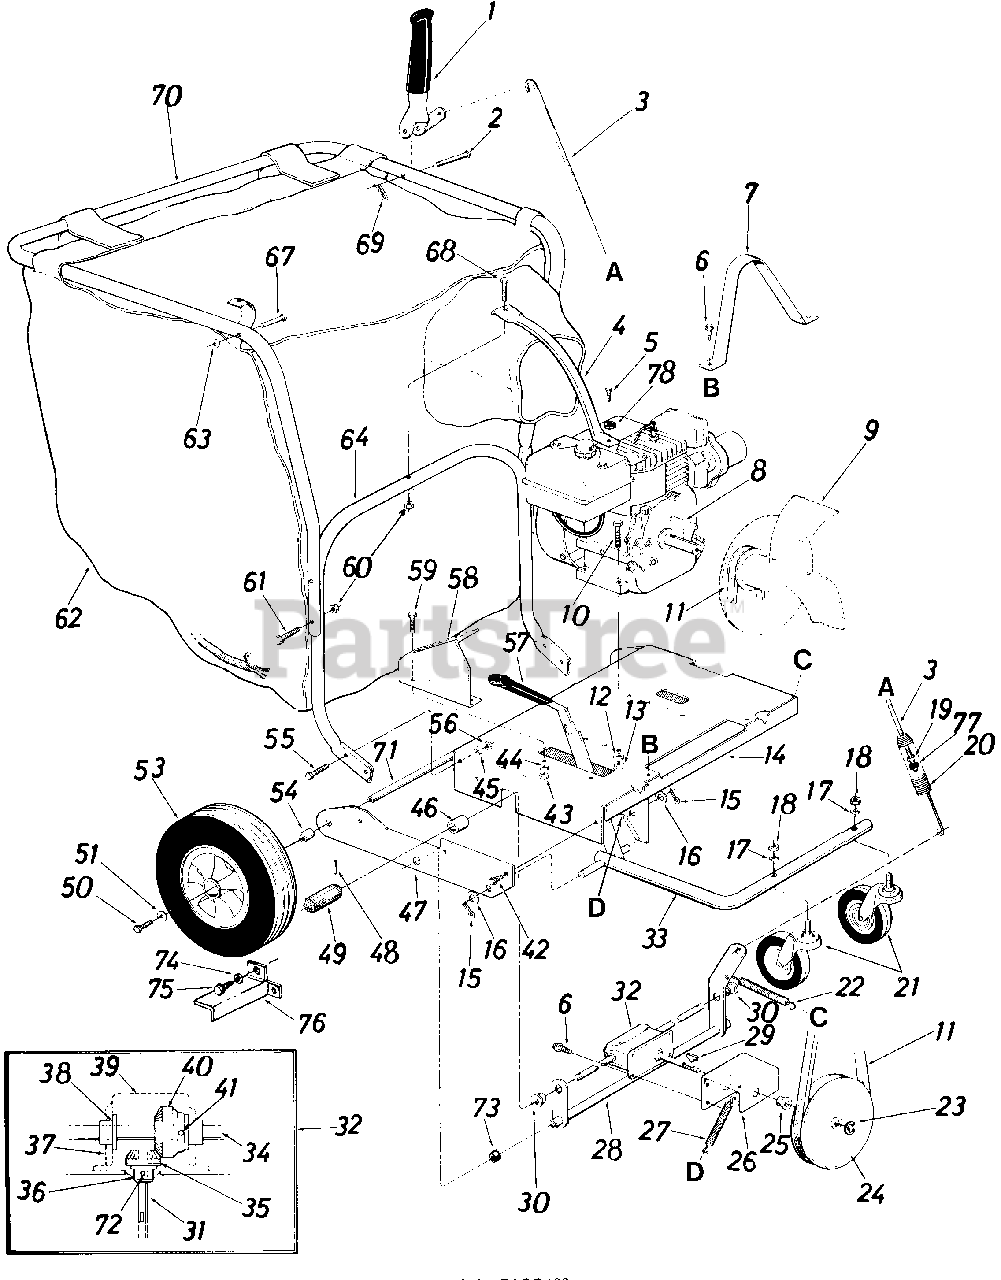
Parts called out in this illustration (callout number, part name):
1	Clutch Grip Ass'y.
2	Clevis Pin .375" Dia. x 1.88" Lg.
3	Clutch Rod 32" Lg.
4	Handle Brace
5	Part of Engine
6	Hex Wash. Hd. AB Tap Scr. 1/4" x .62" Lg.
9	Air Vane Plate Ass'y.
10	Hex Bolt 5/16-18 x 1.50"*
11	"V"-Belt 1/2" x 26" Lg.
12	L.-Wash. 5/16" I.D.*
13	Hex Nut 5/16-18 Thd.*
14	Engine Mounting Frame Ass'y.
15	Cotter Pin 1/8" Dia. x 1.0"
16	Fl.-Wash. .63" I.D. x 1.25" O.D.
17	L.-Wash. 1/2" I.D.*
18	Hex Nut 1/2-13 Thd.*
19	Hex Cent. L.-Nut 1/4-20 Thd.
20	Extension Spring .78" O.D. x .750" Lg.
21	Swivel Caster Wheel 5" Dia. x 1.25"
22	Extension Spring .38" O.D. x 7.50" Lg.
23	Snap "E"-Ring .50" Dia. Shaft
24	"V"-Pulley 5/8" x 6.50" O.D.
25	Flange Bearing .502" I.D.
28	Clutch Bracket Ass'y.
29	#2 Woodruff Key 3/32" Dia. x .81" Lg.
30	Hex Flange Bearing Bronze .625" I.D.
31	Pinion Shaft .50" Dia. x 5.0"
32	Gear Box Ass'y. Comp.
33	Caster Arm Ass'y.
34	Drive Shaft .624" Dia. x 22.75" Lg.
35	Bevel Gear .50" I.D. x 14 Teeth
36	Flange Bearing .503" I.D.
37	Gear Box
38	Flange Bearing .630" I.D.
39	Gear Box Cover
40	Bevel Gear .62" I.D. x 28 Teeth
41	Spring Pin Spiral 3/16" Dia. x 1.25" Lg.
42	Hex Wash. Hd. "AB" Tap Scr. 5/16" x .75" Lg.
43	Hex Nut 5/16-18 Thd.*
44	L.-Wash. 5/16" I.D.*
45	L.-Wash. 5/16" 1. D .*
46	Spacer .63 I.D. x .88" O.D. x .56" Lg.
49	Drive Pinion
50	Hex Locking Bolt 5/16-24 x .62" Lg.
51	Fl. ash. .34" I.D. x 87" O.D.
53	Wheel Ass'y.-Comp. 12" x 3"
54	Spacer .63" I.D. x 1.00" O.D. x .94" Lg.
55	Hex Bolt 5/16-18 x .75" Lg.
56	Hex Nut 5/16-18 Thd.*
57	Flat Grip Vinyl
58	Index Plate
59	Hex Bolt 5/16-18 x .75" Lg.*
60	Hex Cent. L.-Nut 1/4-20 Thd.
61	Hex Bolt 1/4-20 x 1.75" Lg.
62	Vacuum Bag-Felt
63	Push Speed Nut .25" Dia. Stud
64	Lower Handle
67	Stud Pin .250" Dia. x 1.75"
68	Hex Bolt 1/4-20 x 1.75" Lg.*
69	Internal Cotter Pin 3/8" Dia.
70	Upper Handle
71	RearAxle .624'l Dia. x 24.37'
72	Spring Roll Pin 5/32" Dia. x 1.1-2
73	Spacer .82" I.D. x 1.00" O.D. x .305 Lg.
74	L.-Wash. .265" I.D.
75	Hex Self Tap Scr. 1/4" x 3/8" Lg.
78	Belleville Washer
